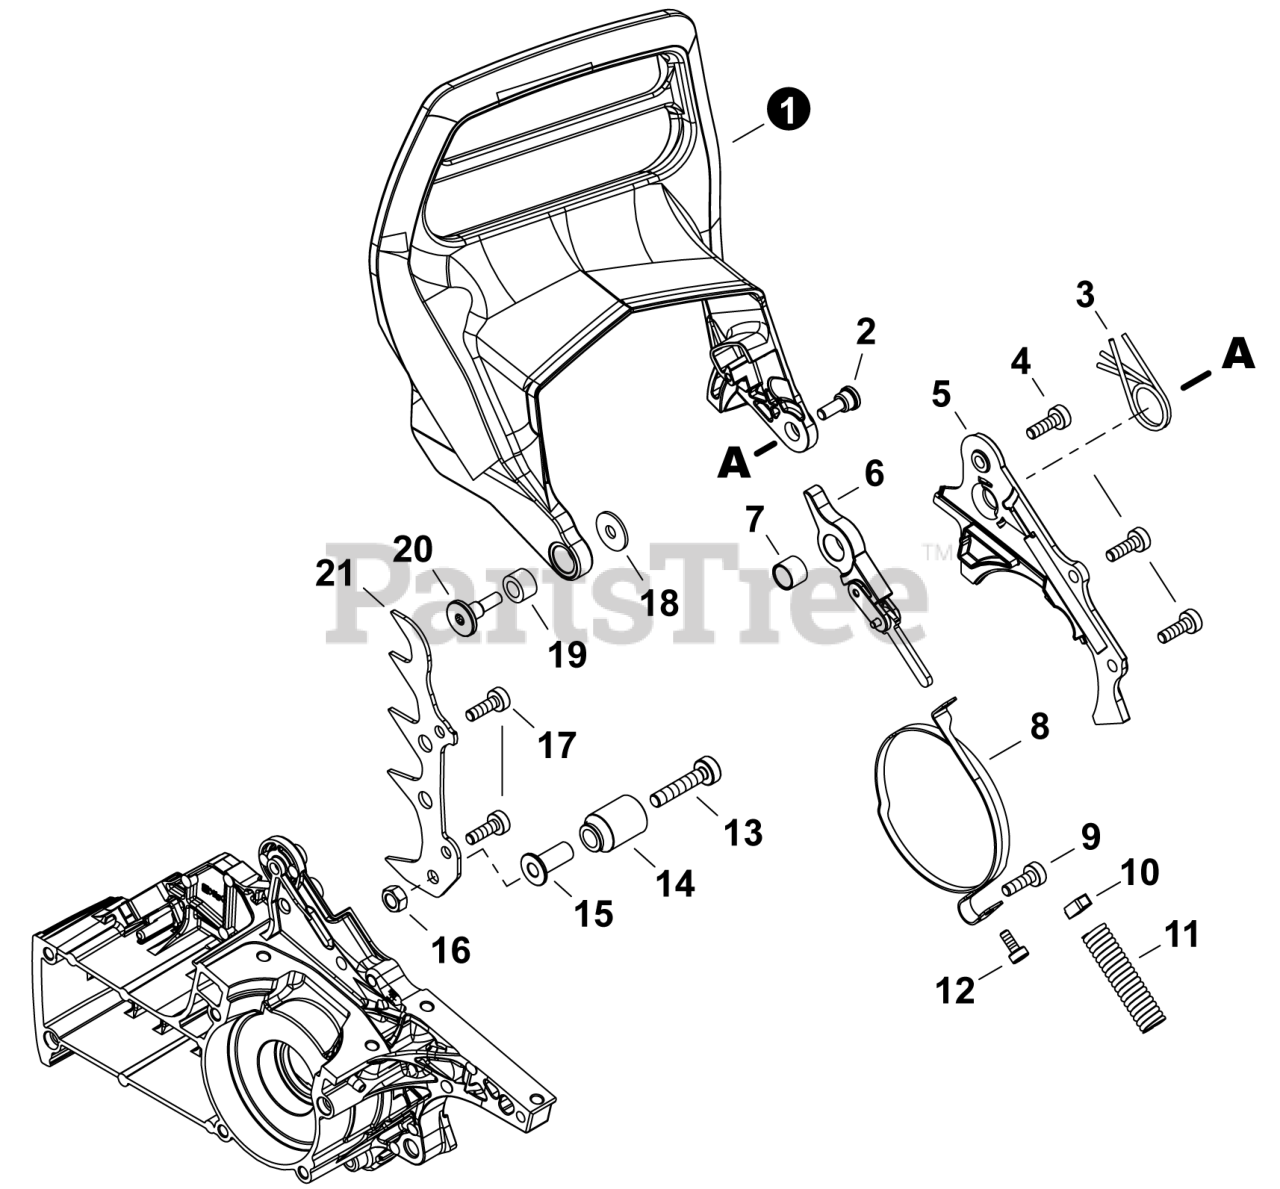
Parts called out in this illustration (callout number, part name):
1	LEVER, BRAKE
3	SPRING, TORSION
4	BOLT, TORX 5x16
5	COVER, BRAKE
6	CONNECTOR, BRAKE
7	SPACER 12x10xT: 1.0
8	BAND, BRAKE
9	BOLT, TORX 5x16
11	SPRING, COMPRESSION 12x70.5
12	BOLT, TORX 4x10
13	BOLT, TORX 6x30
14	CATCHER, CHAIN
15	COLLAR 6
16	NUT, LOCK 6
17	BOLT, TORX 5x16
18	WASHER 5
21	SPIKE, BUMPER
